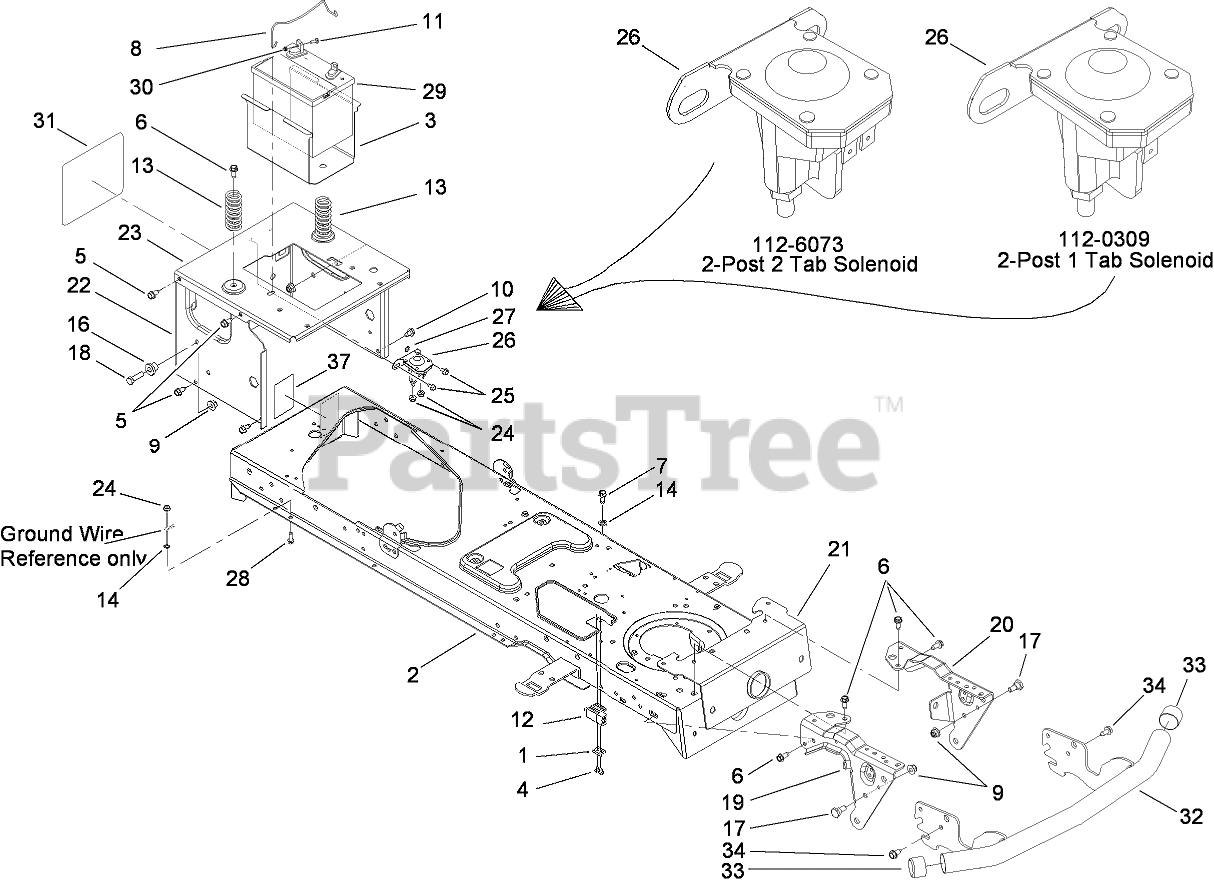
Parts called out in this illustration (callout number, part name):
1	PLATE-SWITCH
2	LOWER FRAME ASM
3	TRAY-BATTERY
4	SCREW-TAP
5	SCREW-HWH
6	SCREW-HWH
7	SCREW-HWH
8	ROD-HOLDDOWN, BATTERY
9	NUT-LOCK, FLANGE
10	SCREW-TAP
11	BOLT-CARRIAGE
12	SWITCH-INTERLOCK
13	SPRING-COMPRESSION
14	WASHER-LOCK, EXTERNAL
16	SPACER-SHOULDER
17	BOLT-SHOULDER
18	SCREW-HH
19	BRACKET-PIVOT, SUPPORT
20	BRACKET-PIVOT, SUPPORT
21	BRACKET-PIVOT, BAR
22	SUPPORT-FRAME, REAR
23	BRACKET-FRAME, SEAT
24	NUT-LOCK, FLANGE
25	SCREW-HWHTF
26	SOLENOID-12V, 2 Post 1 Tab
26	SOLENOID-12V, 2 POST 2 Tab
27	WASHER-LOCK, EXTERNAL
28	SCREW-TAP
29	BATTERY-245, CCA (DRY FLAT TOP)
30	NUT-SEMS
31	DECAL-TORO
32	BUMPER ASM
33	CAP-HUB
34	SCREW-HH, TAP
37	DECAL-HYDRO, TOE VALVE
